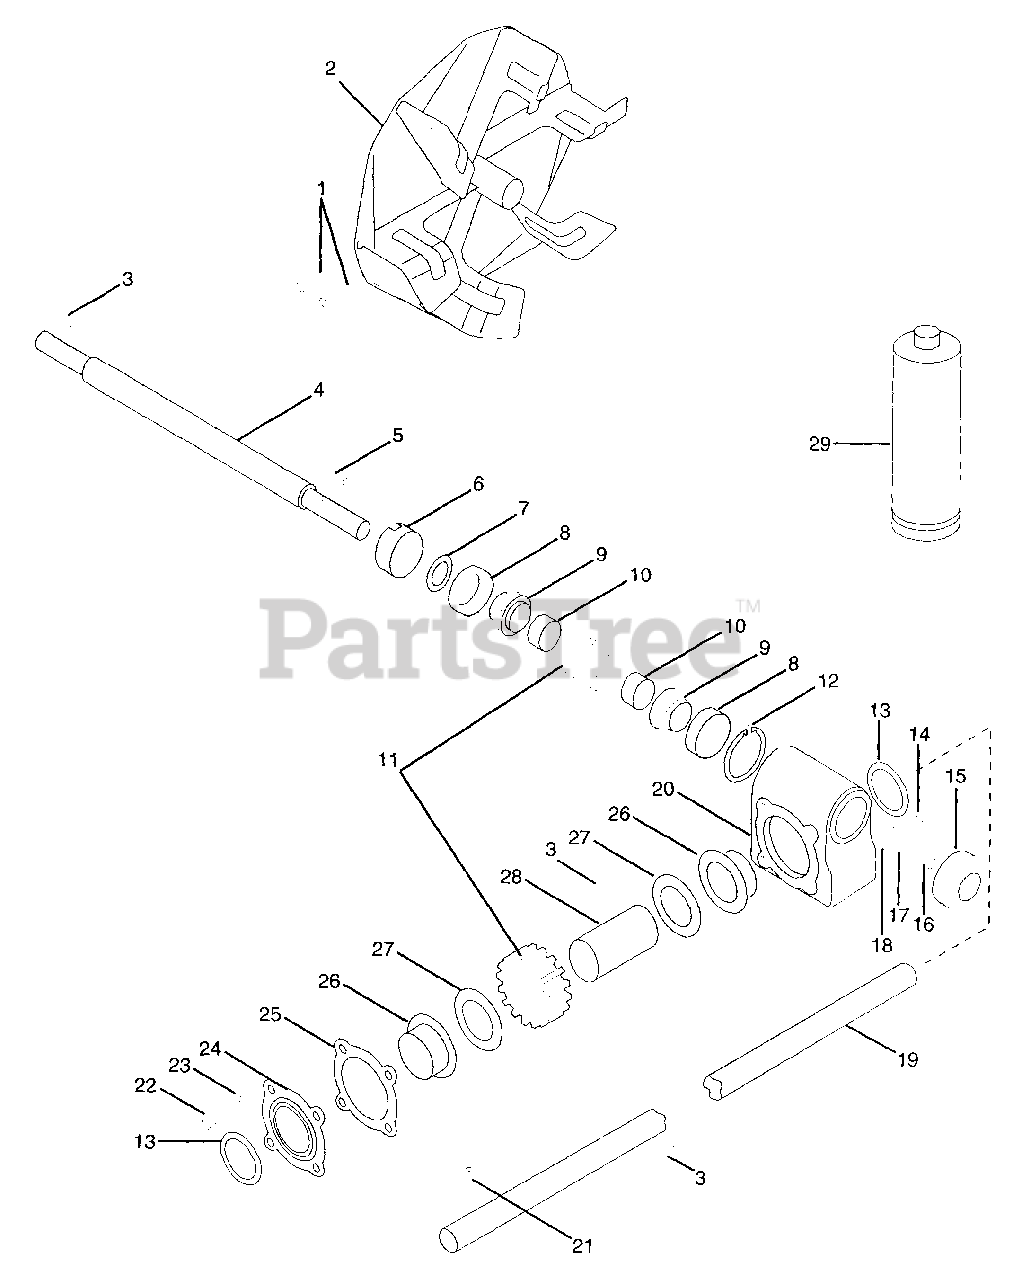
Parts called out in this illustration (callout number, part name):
1	PIN-ROLL .313X1.75
2	FAN - 14"
3	KEY-WDRF .25X.875X.375 SAE A
4	WORM SHAFT
5	KEY-SQ .188X1.0X.188 SAE 8630
6	ADJUSTMENT PLUG - 1" SHAFT
7	SEAL 1.000X1.312X.150
8	BRG-CUP 1.781X.475
9	BRG-CONE .750X.61
10	BSHG, SPCR .755X1.12X.50 PM
11	WORM & GEAR SERVICE ASSEMBLY
12	RG-RTNG-INT 1.781X.062
13	SEAL 1.625X2.125X.250
14	PIPE PLUG
15	DUST CAP
16	BLT-HEX .31-18X.75 PL GR2
17	WSHR-LK .312X.097 PL HVY
18	WSHR-FL-STL .328X1.0X.094
19	SHAFT, 36" RAKE - 1.00 DIA.
20	GEAR CASE - CAST IRON
21	PIN-ROLL .188X1.50
22	BLT-HEX .25-20X.75 PL GR2
23	WSHR-LK-EXT. 250 ID
24	GEAR CASE COVER
26	BSHG-FLG .683X1.87X1.68X2.250
27	WSHR-FL-STL 1.625X2.500X.012
28	GEAR CASE SHAFT
29	ARIENS 16 OZ.BOTTLE OF L2 LUBE
